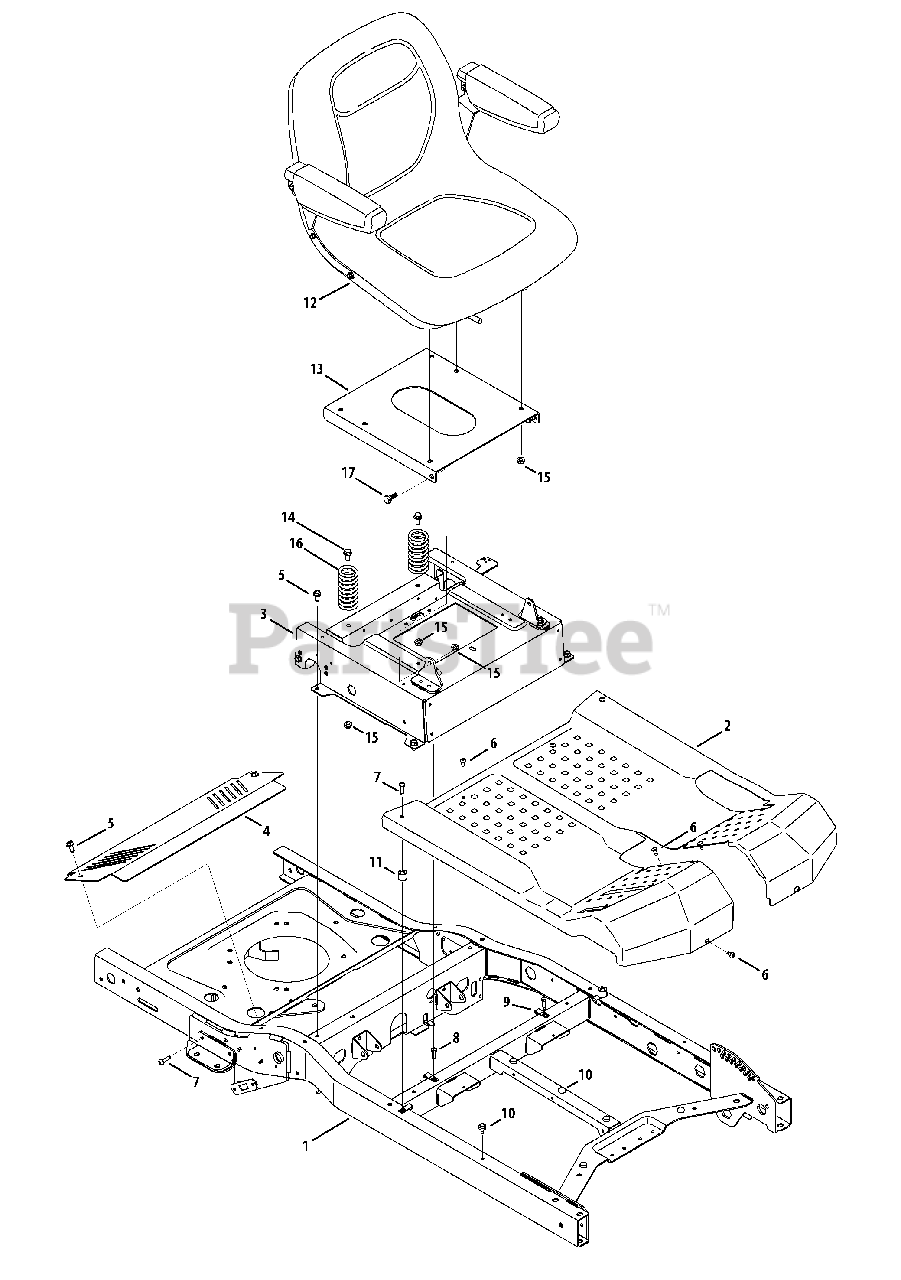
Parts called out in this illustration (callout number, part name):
1	Frame Assembly
3	Seat Box Assembly
4	Transmission Cover
5	Hex Washer Screw, 5/16-18 x .750
6	Screw, 1/4-20 x .5
7	Screw, 1/4-20 x 1.0
8	Hex Screw, 1/4-20 x .625
9	Speed Nut, U-Type 1/4-20
10	Rubber Bumper
11	Spacer, .281 x .750 x .680
12	Seat w/ Armrests
14	Hex Washer Screw, 5/16-18
15	Flange Lock Nut, 5/16-18
16	Comp. Spring, 1.71 x 3.735 x .238
17	Shoulder Screw, 5/16-18 x .437 x .268
